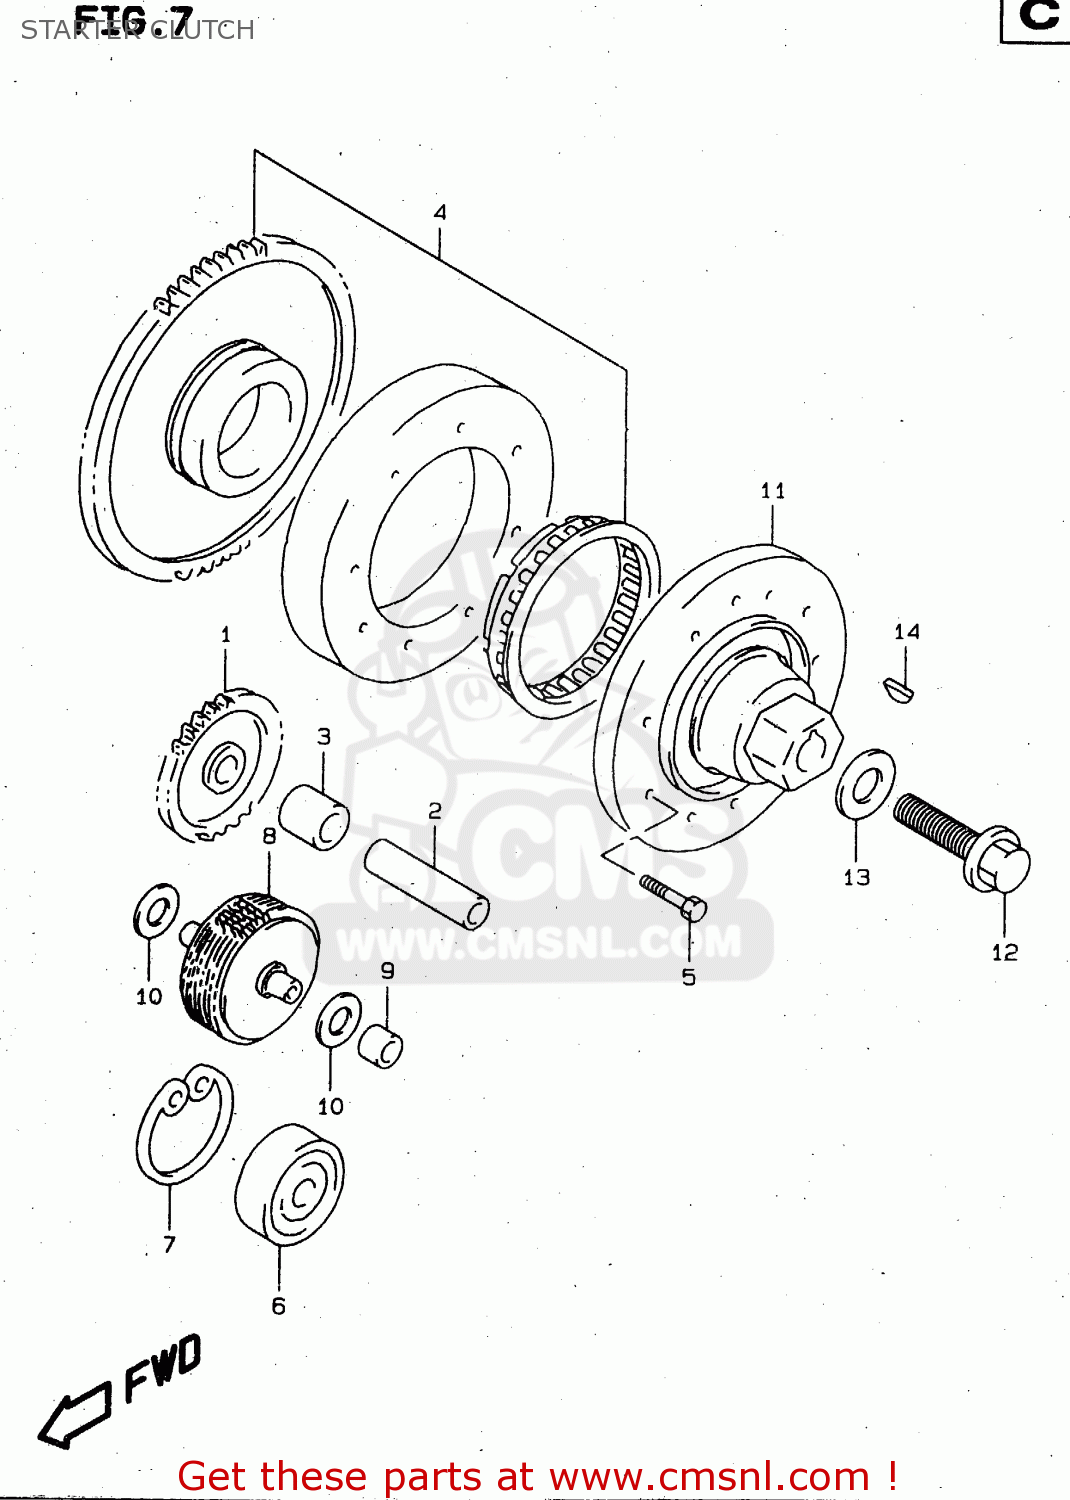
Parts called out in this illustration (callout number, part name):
1	GEAR,STARTER IDLE NO.2
2	PIN(7X12X50.5)
3	SPACER(12.5X19X17.5)
4	CLUTCH SET,STARTER
5	BOLT
6	BEARING(12X28X8)
7	CIRCLIP
8	LIMITER ASSEMBLY,STARTER IDLER GEAR
9	BUSH,LIMITER GEAR SHAFT
10	WASHER
11	HOUSING,STARTER CLUTCH
12	BOLT(12X40)
13	WASHER(12X30X3)
14	KEY
